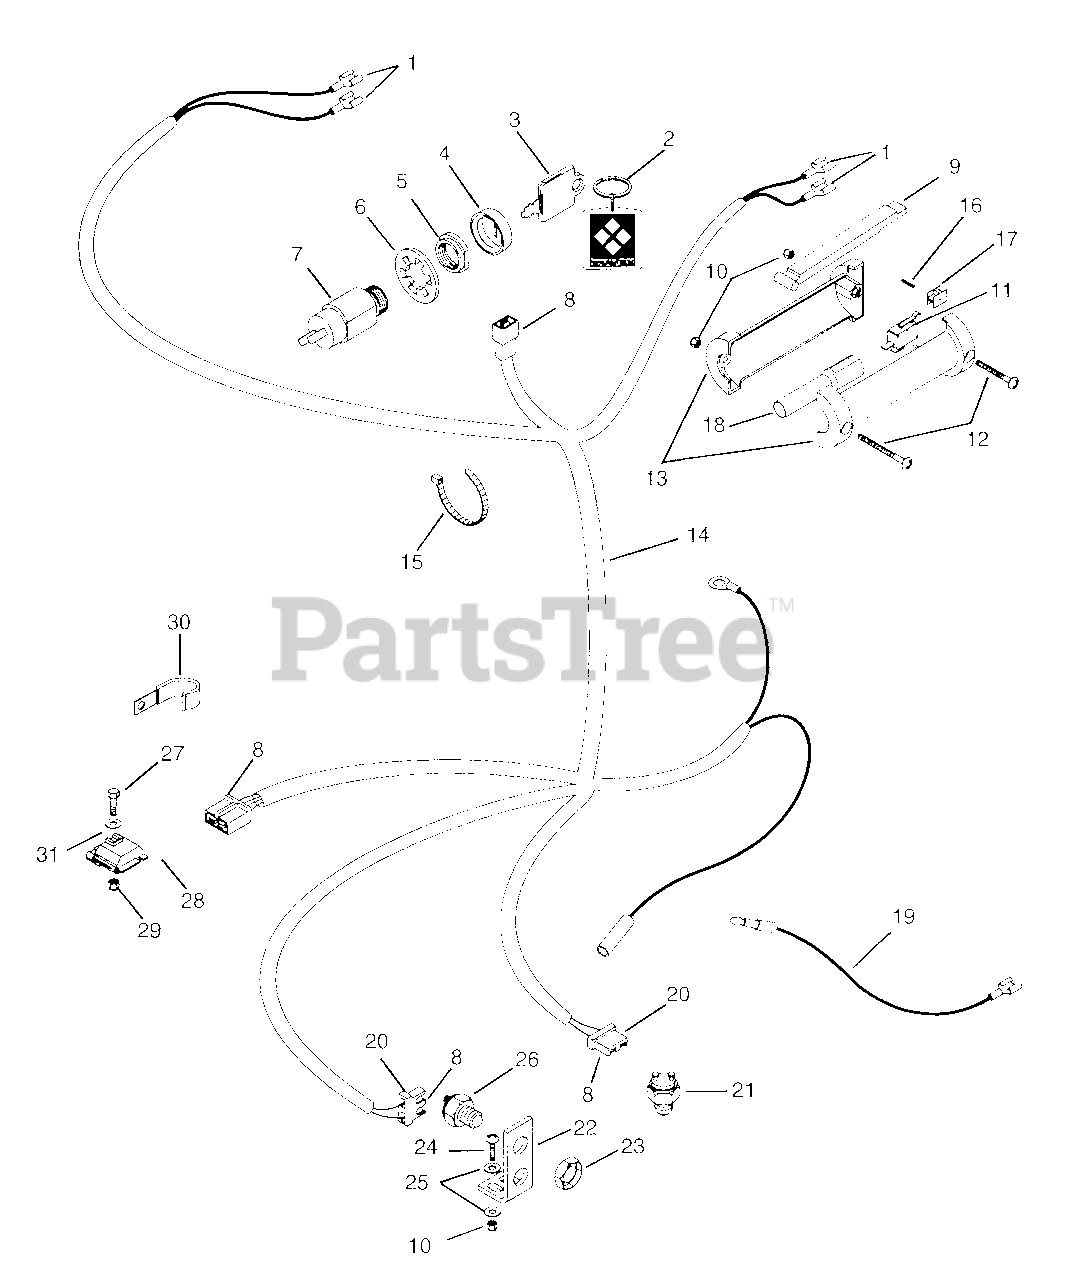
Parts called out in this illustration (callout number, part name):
1	Terminal-Female
2	Key Chain
3	Ignition Switch Key
4	Cap-Ignition Switch
5	Nut-Panel .625-32
6	Washer-Lock .625
7	Key Switch Assembly
8	Terminal
10	Nut-Locking-Nylon w/Insert 10-24
12	Screw-Machine-Pan Head 10-24 x 1.50
13	Handle-Left Hand & Right Hand
14	Harness-Wiring Pro Recoil
15	Tie Wrap-Black
16	Pin-Roll .094 x .750
17	Holder-Switch
18	Insert-Handlebar
19	Wire-Ground (086)
20	Connector 2-Wire Switch
21	Switch-Neutral Start (N.C.)
22	Bracket-Interlock Switch
23	Nut-Stamped .56-18
24	Bolt-Hex 10-24 x .75
25	Washer-Flat-Steel .219 x .50 x .049
26	Switch-Neutral Start
27	Bolt-Hex .25-20 x .75 Grade 5
29	Nut-Locking-Center .250-20
31	Washer-Flat-Steel .344 x .688 x .065
